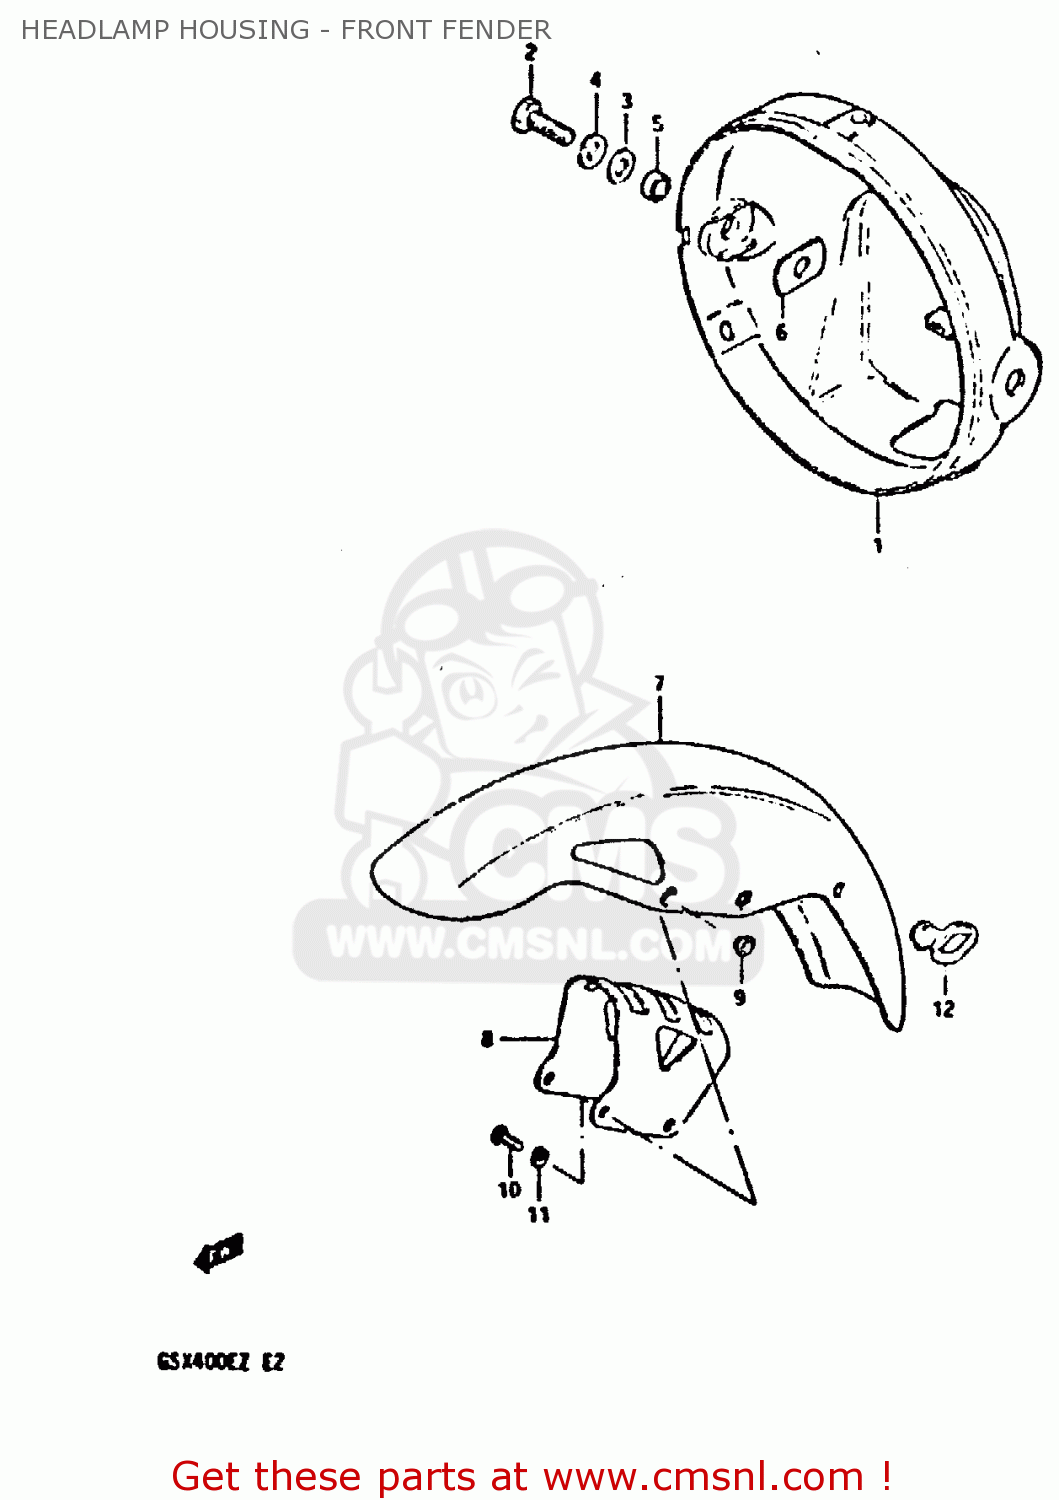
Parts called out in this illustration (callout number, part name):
1	HOUSING,HEADLAMP
2	BOLT
3	WASHER
4	LOCK WASHER
5	SPACER (8.8X12X7)
6	CUSHION
7	FENDER, FRONT
8	BRACE,FRONT FENDER
9	WASHER
10	BOLT
11	LOCK WASHER
12	GUIDE,CABLE
